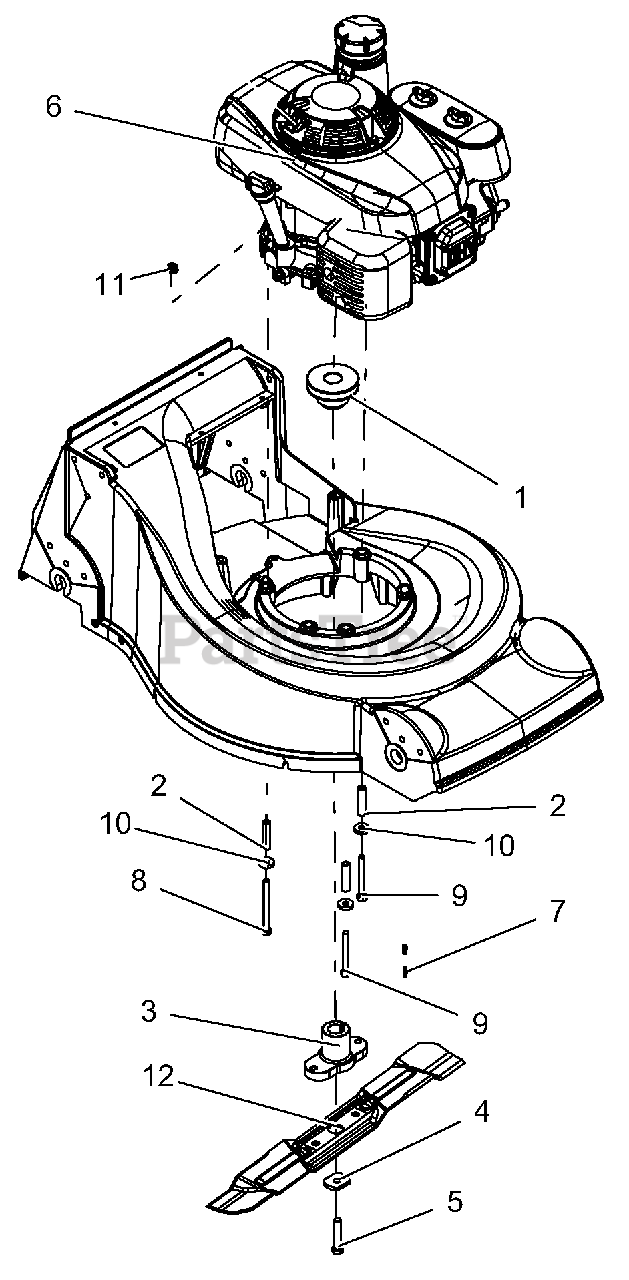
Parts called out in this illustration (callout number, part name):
1	PULLEY, GROUND DRIVE-WLDMT
2	BSHG, SLV .322 X .438 X 1.824
3	ADAPTOR, BLADE
4	WSHR, SPRG
5	BLT-HEX .38-24X2.00 YWZC GR8
6	ENGINE, HONDA ZONE-CARB
7	KEY-WDRF .156X.625X.25 SAE 6
8	BLT-HEX .31-18X3.50 GR5 YWZC
9	BLT-HEX .31-24X2.75 GR5 YWZC
10	WSHR-FL-STL .328X.87X.179 YWZC
11	NUT, LK-TOP-FLG .312-18 YWZC
12	BLADE, MOWER 21" HIGH-LIFT
